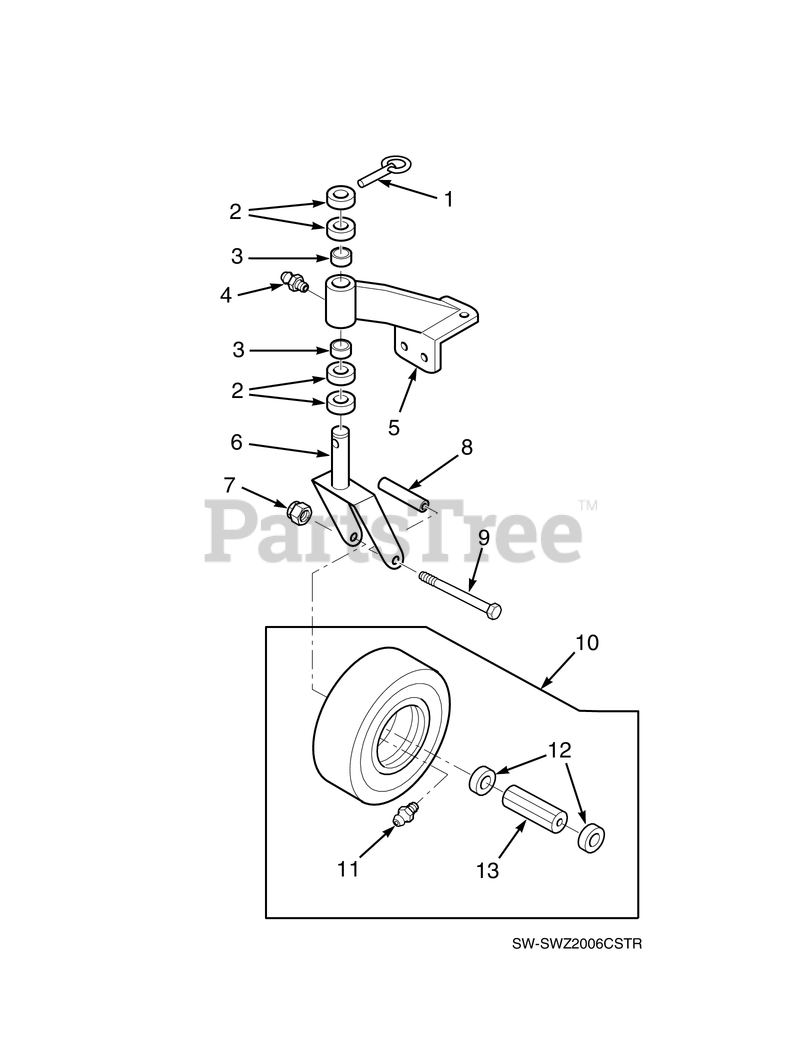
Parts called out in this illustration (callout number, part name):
1	Quick Pin, .438" Dia.
2	SPACER, CASTER YOKE, 1/2" THICK
3	Bronze Bushing, 7/8 ID x 1.0 Flanged
4	GREASE FITTING, STR. 1/4-28 SELF TAP.
5	Support Assembly
6	Caster Yoke Weldment
7	HEX LOCKNUT, ELASTIC STOP, 1/2-13
8	SLEEVE, CASTER WHEEL BEARING
9	Bolt, Hex Head 1/2-13 x 5-1/2" (Three Weights Installed)
10	REPLACED BY 9275
11	GREASE FITTING, 45 DEGREE 1/4-28
12	Retainer, Bearing, Caster Wheel
13	Roller Bearing, .625 x 3-1/4"
